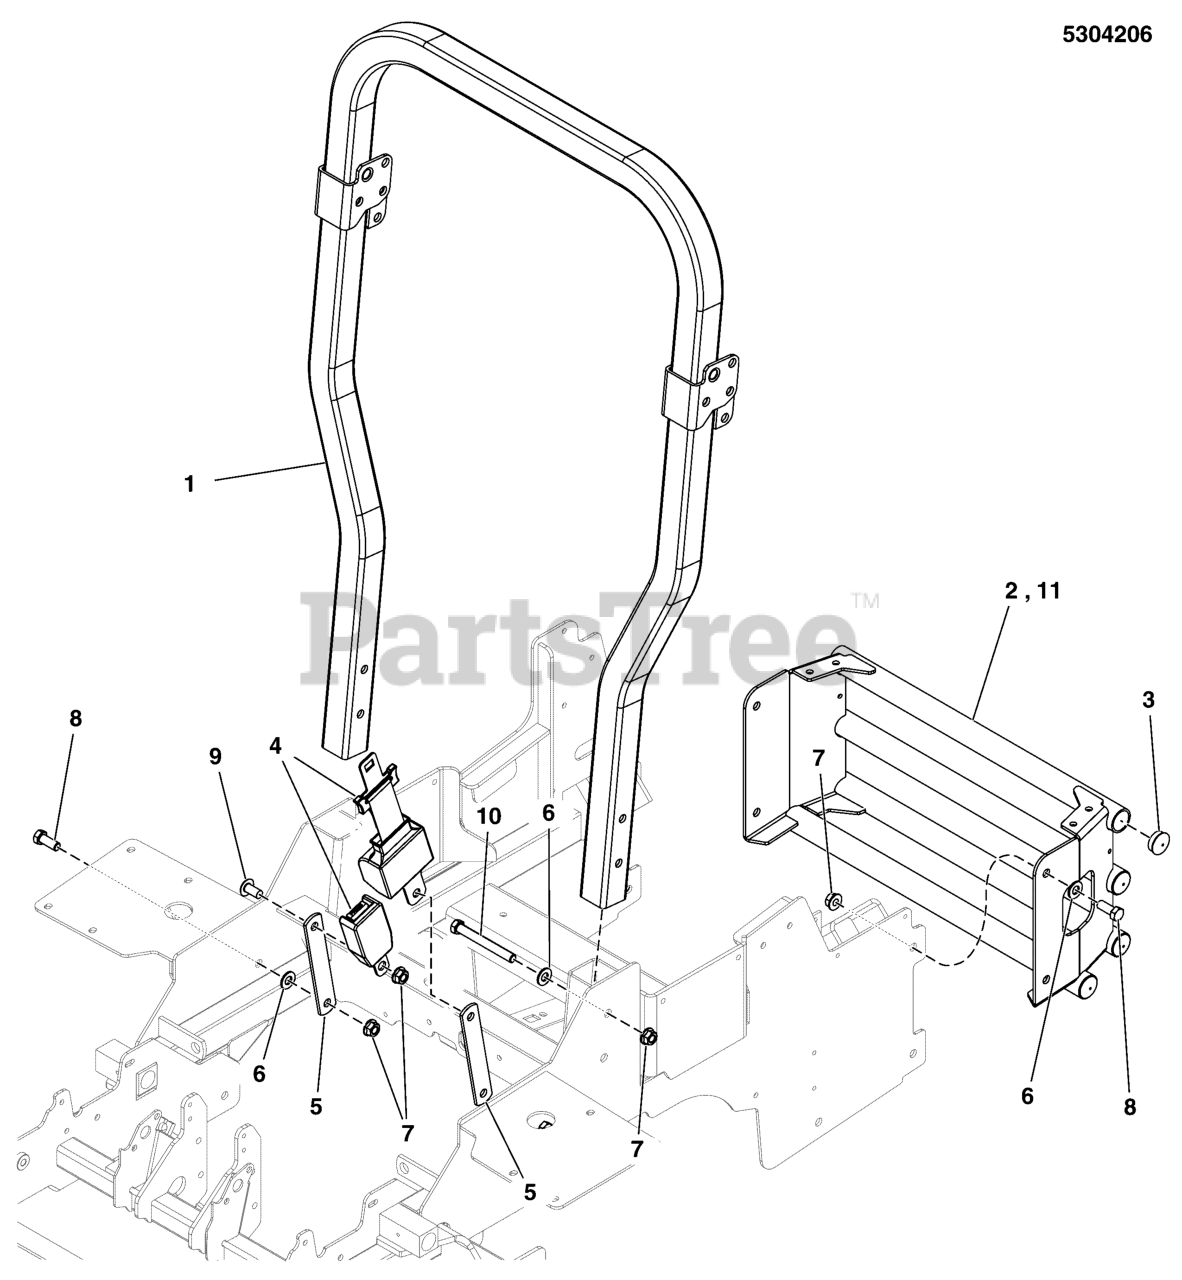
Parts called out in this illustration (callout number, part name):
2	WELD, BUMPER, IS2600 - RED
3	PLUG, PANEL, 1.25 - BLACK
4	SEAT BELT, RETRACTING - ASSM
5	BAR, MOUNT, SEAT BELT, IS700Z - BLK
6	WASHER, 1/2 SAE
7	NUT, Hex Flange, Nylock, 1/2-13
8	BOLT, 1/2-13 X 1-1/4 GD5 CZ
9	SCREW, 1/2-13 X 1.00, SHCS
10	BOLT, 1/2-13 X 3-1/2, HEX HD, GD5, CZ (SV)
11	WELD, BUMPER, IS2600 - RED
